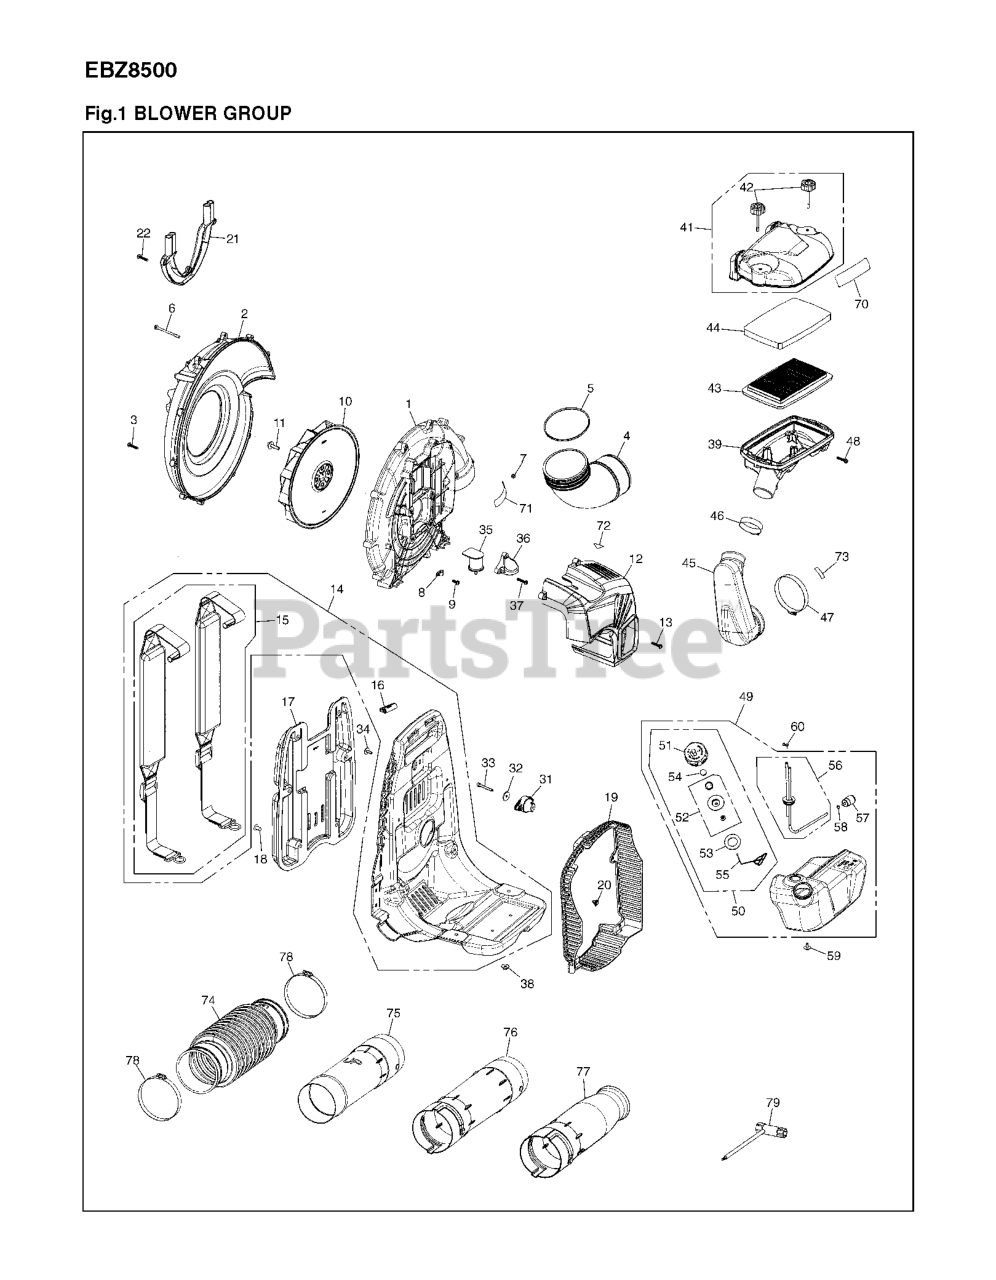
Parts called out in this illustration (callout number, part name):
1	CASE VOLUTE
2	VOLUTE,COVER
5	0-RING
8	CLAMP
10	FAN
11	BOLT
12	ENGINE COVER
14	FRAME ASSY
15	BAND ASSY (RPLS 848L583611)
16	CLIP
18	CLIP
19	NET
20	CLIP
31	DAMPER UPPER
33	BOLT
39	BODY AIR FILTER
41	COVER ASSY
42	KNOB BOLT
43	ELEMENT
44	ELEMENT
45	HOSE
46	CLAMP(F64)
47	CLAMP(F96)
49	TANK ASSY
50	ASSY FUEL CAP
52	HOLDER-A
56	PIPE
57	FILTER ASSY
58	CLIP
60	CLIP
70	DECAL, CLEANER
73	LABEL,CHOKE
74	HOSE
77	PIPE,END
78	CLAMP(F115)
79	SOCKET
